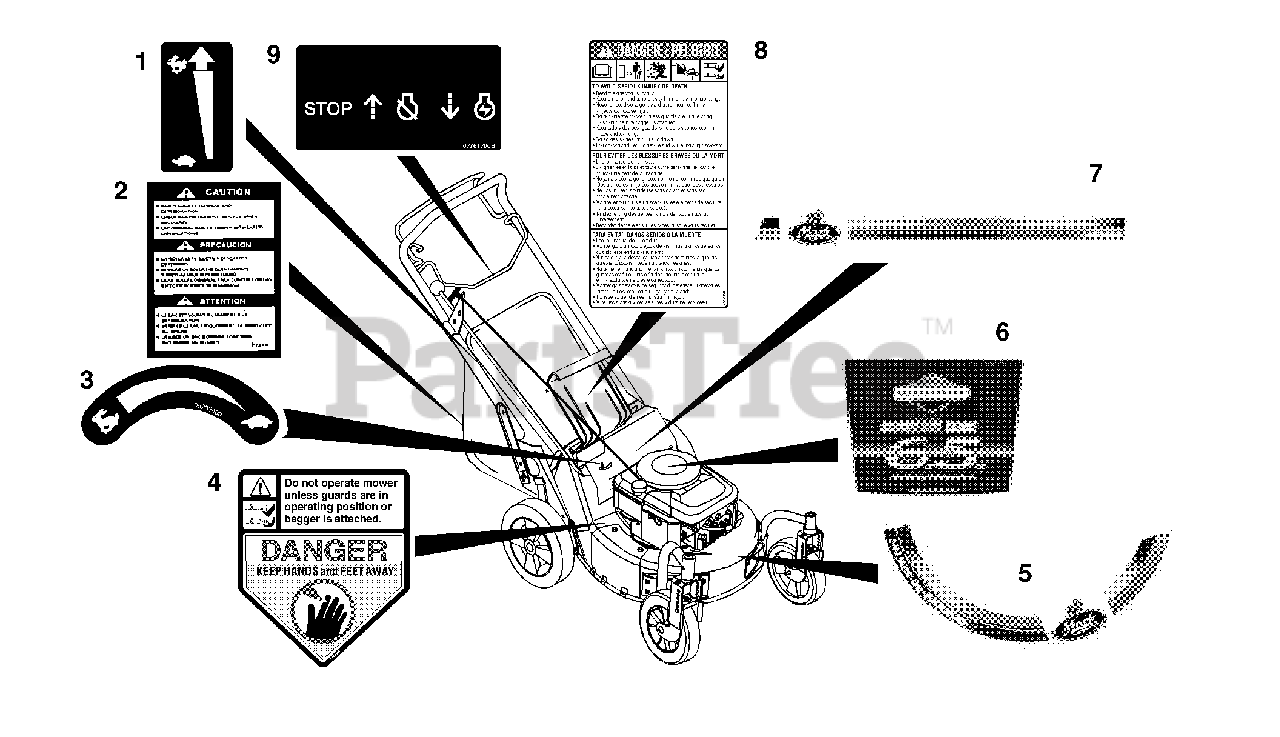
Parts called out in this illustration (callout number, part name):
1	DECAL-SPEED CONTROL
2	LABEL - BAGGER 21"
3	DECAL, TURTLE & RABBIT
4	DECAL, CPSC DANGER
5	DECAL, DECK MACK
6	DECAL, BRIGGS QUANTUM 6.5
7	DECAL, MACK DRIVE COVER
8	DECAL, BILINGUAL DANGER
9	DECAL - ENGINE CONTROL
